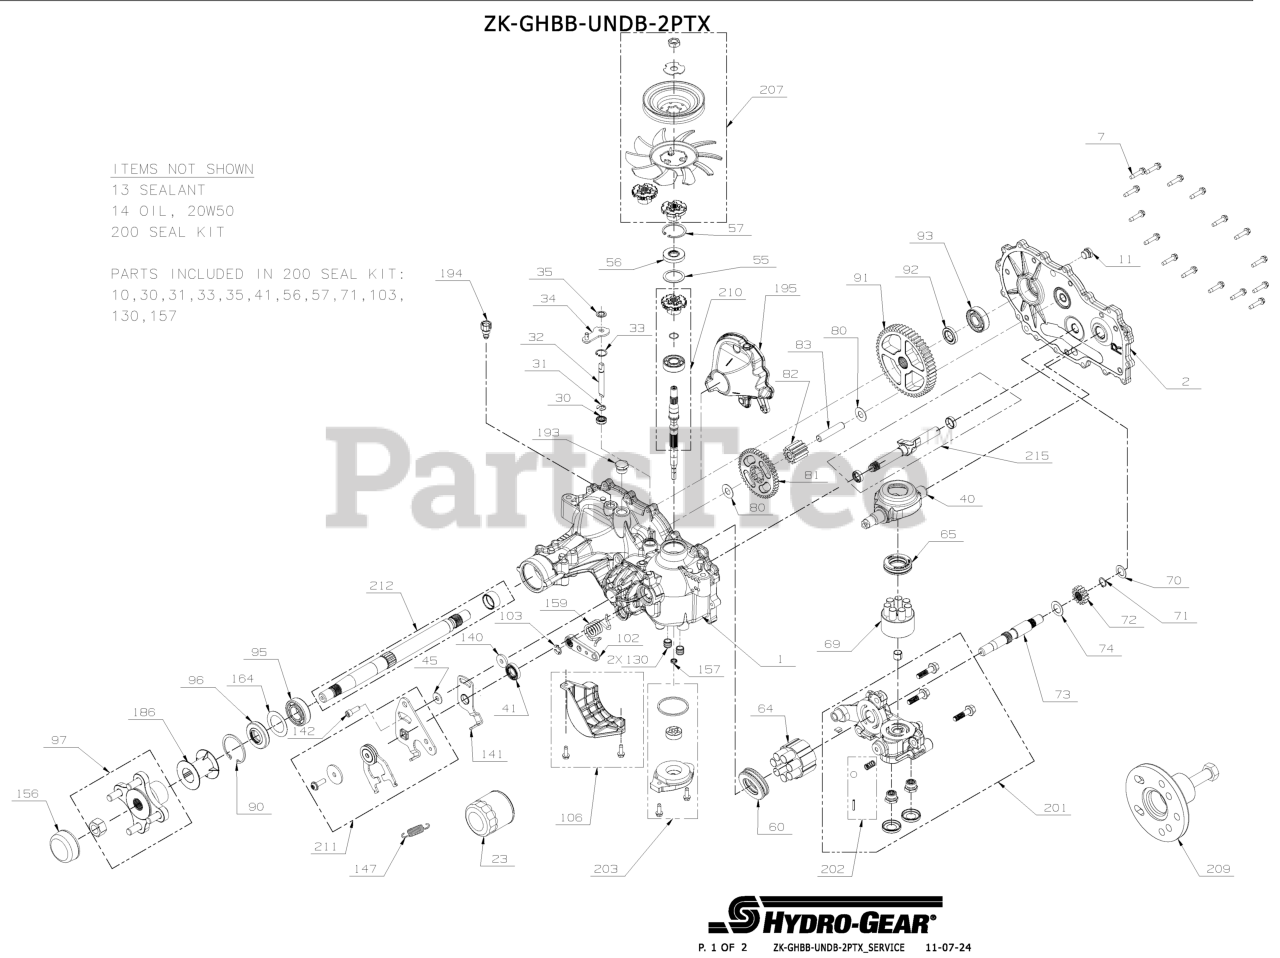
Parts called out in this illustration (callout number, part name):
1	KIT, HOUSING, MAIN, RH, CHRG, CNTL
2	KIT, SIDE COVER, RH
7	SCREW,HEX WASHER 1/4-20X1.125
11	PLUG, EXTERNAL HEX VENT 9/16-18
13	SEALANT TUBE 10.1OZ.
14	FLUID, HYDRO 15W50 QT
14	FLUID, HYDRO 20W50 QT
23	FILTER, HYDRO-GEAR 2800 TRANS
30	SEAL, LIP .375 X .75 X .25
31	RING. RETAINING
33	RING, RET .750
34	ARM, BYPASS
35	RING, RTNG .
40	TRUNNION, SWASHPLATE
41	SEAL, LIP 18X32X7
55	WASHER 1.23X1.56X.04
56	SEAL, LIP 17 X 40 X 7 HNBR
57	RING, RET 1.56 INT
60	HG THRUST BEARING (51462)
64	HG 16CC CYLINDER BLOCK (71579)
65	BEARING. THRUST 30 X 52 X 13
69	ASSY, BLOCK 7 PISTON
70	WASHER .63X1.0X.05
71	RING, RET 62 EXT
73	SHAFT, MOTOR
74	WASHER .71 X 1.16 X .04
80	WASHER .5X1.0X.032
83	PIN, JACKSHAFT
90	RING, RETAINING
93	KIT, BEARING
95	BEARING, BALL 25.4 X 52 X 15
96	SEAL, LIP
97	KIT, HUB 4 BOLT
102	HANDLE- ACTUATING
103	CLIP,BRAKE ARM HYDROGEAR 52027
106	KIT, FILTER GUARD
130	TUBE, CHARGE TRIPLE O-RING
141	ARM, NEUTRAL RIGHT
142	SHCS 5/16-24X1 PATCH
147	SPRING, EXTENSION
156	SPRING, TORSION, CW
157	KIT, GEROTOR SEAL
159	SPRING TORS 1.01X1.17
164	WASHER, 1.355 x 2.035 x .021 FLAT
186	TUBE, AXLE 2.03
194	KIT, CENTER SECTION, LH
195	KIT, FAN/PULLEY
200	KIT, SEAL
201	KIT-CENTER SECTION-RH-CHRG
202	KIT, CHARGE RELIEF
203	KIT, CHARGE
207	KIT- FAN/PULLEY
209	HUB PULLER 5 BLT HYDGEAR 72320
210	KIT, INPUT SHAFT
211	KIT, RTN BIDIRECTIONAL
212	KIT, SHAFT, AXLE
215	OUTBOARD, RH ROT B / LH ROT A
